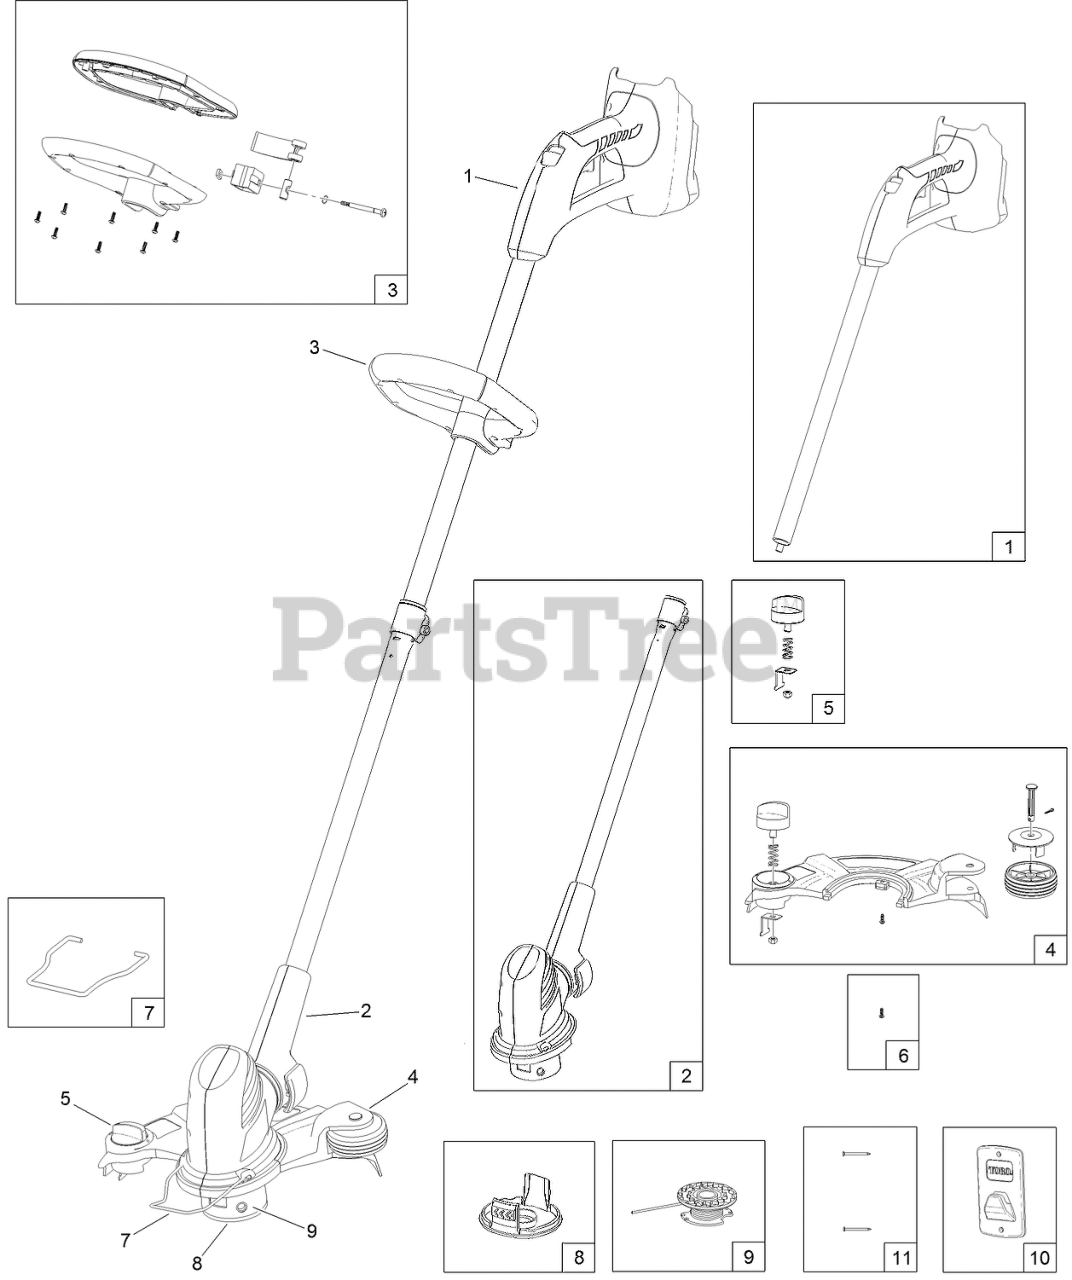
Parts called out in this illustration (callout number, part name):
1	HANDLE-UPPER
2	HOUSING-MOTOR, LOWER
3	ASSIST HANDLE ASM
4	SHIELD ASM
5	KNOB-SAVER, POWER
7	CLIP-GUIDE, EDGER
8	CAP-RETAINER, SPOOL
9	SPOOL-REPLACEMENT
10	BRACKET-MOUNT, WALL
11	SCREW (Wall Mount Bracket)
